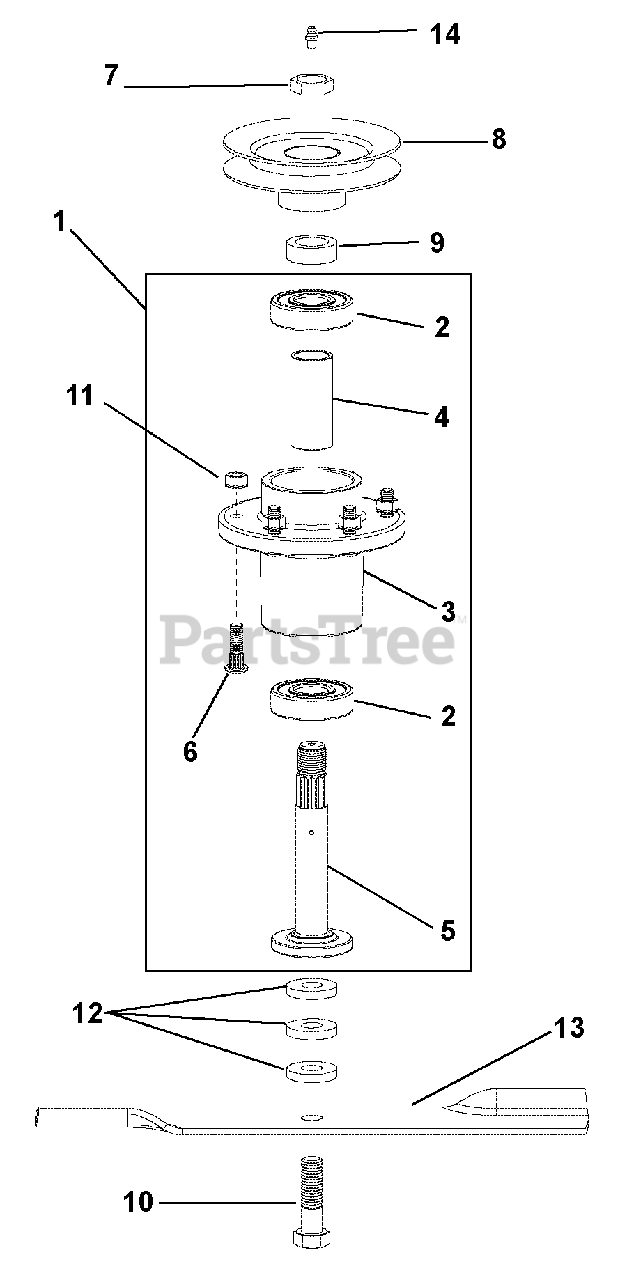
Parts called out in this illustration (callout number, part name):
1	Spindle Assembly (Includes Items 2, 3, 4, 5, and 14)
2	Ball Bearing
3	Housing
4	Spacer, 1.000 x 1.250 x 2.772
5	Shaft, Spindle
6	Bolt, 3/8 x 1.25 RIB
7	Nut, Pulley (Special)
8	Pulley, Cutter Housing - Refer to "Deck Assembly"
9	Spacer, Pulley
10	Bolt, Hex .62-11 x 2.25
11	Nut, Hex .31-18
12	Spacer, Blade Bolt
13	18.0" Blade, 52" Deck
14	Zerk, Grease S/O
